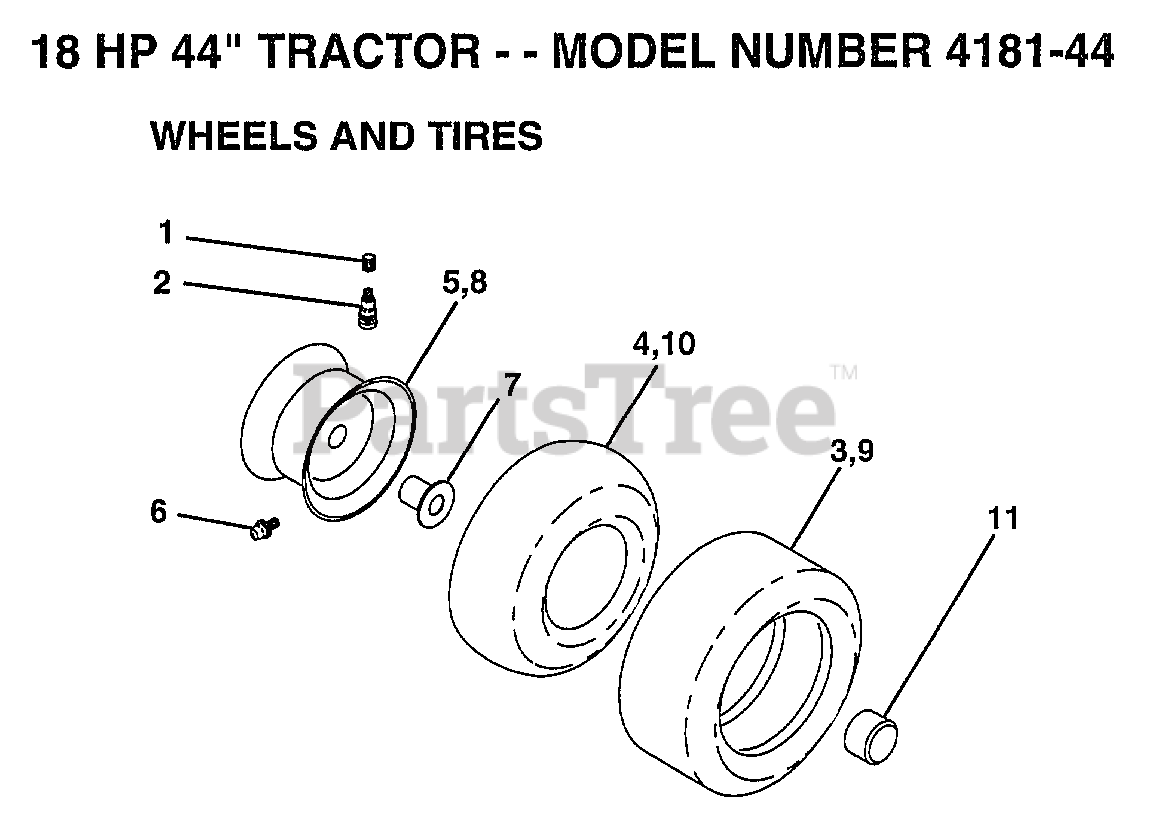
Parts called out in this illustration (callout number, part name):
1	VALVE CAP
2	VALVE STEM LT
4	TUBE.5.3/4.5/6
5	RIM.FRONT.
6	FITTING LT
7	"FLANGE, BEARING"
8	RIM.REAR.417
10	TUBE.23X8/10-12
11	HUB CAP
